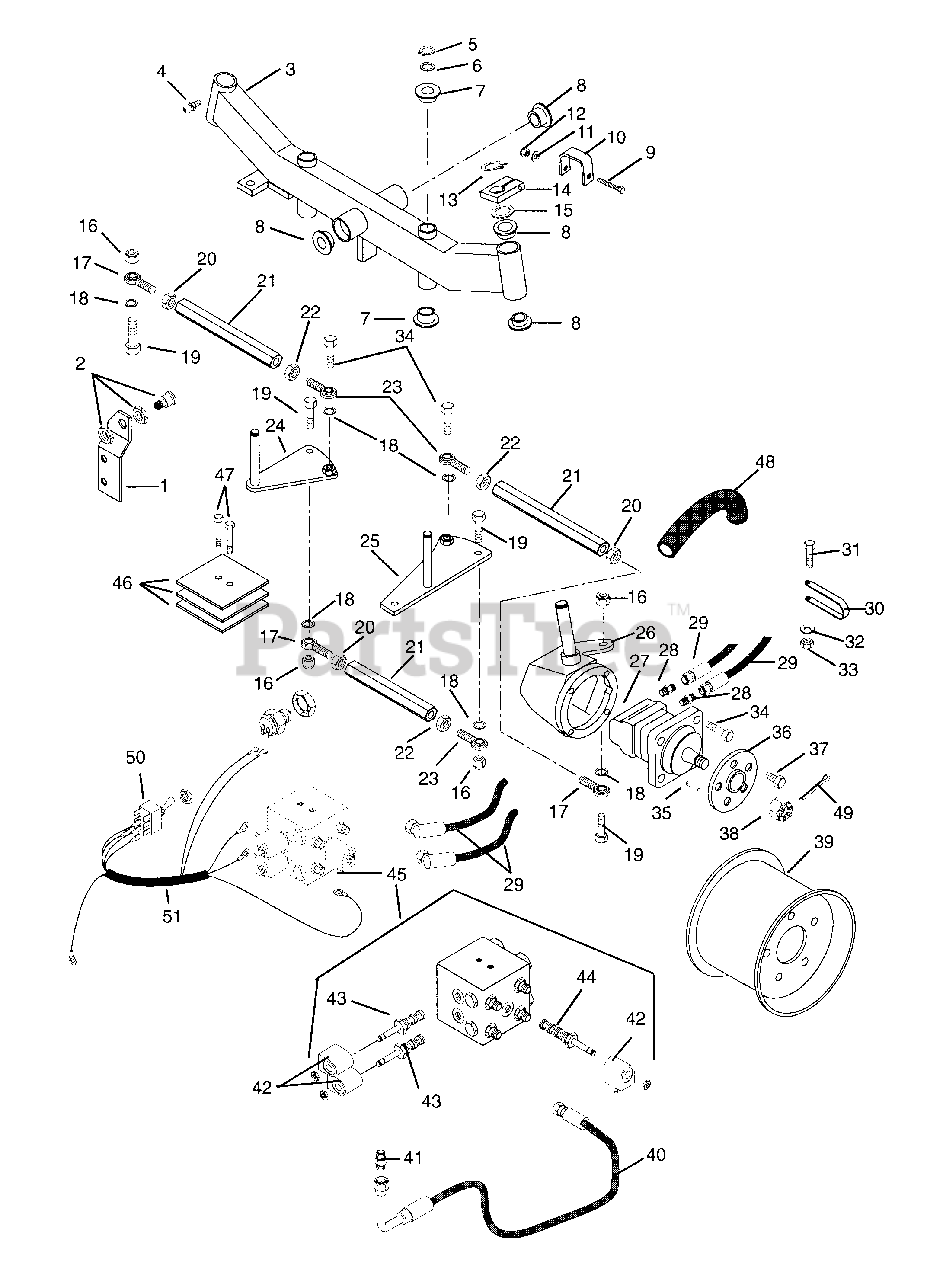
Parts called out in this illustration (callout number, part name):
2	Safety Switch
3	Axle Weldment
4	Fitting Lube .25-28 x .256
5	Ring-Retaining-External .689 x .077
6	Bearing-Needle-Thrust .752 x 1.24 x .031
7	Bushing-Flange .762 x 1.0 x .580 x 1.48
8	Bushing-Flange 1.020 x 1.385 x .75 x 1.75
9	Bolt-Hex .25-20 x 2.75 Grade 5
10	Bracket, Hose Loop
11	Washer-Flat-Steel .281 X .62 X .065
12	Nut-Locking .25-20
13	Ring-Retaining-External .906 x .078
14	Bracket Support
15	Washer-Hardened Thrust 1.002 x 1.552 x .030
16	Nut-Locking-Center .50-13 Grade 5
17	Assembly, Rod End Right Hand
18	Spacer .520 x .625 x .125
19	Bolt-Hex .50-13 x 2.00 Grade 5
20	Nut-Jam .50-20 Grade 2
21	Rod, Tie
22	Nut-Jam .50-20 Left Hand Grade 2
23	Assembly, Rod End Left Hand
24	Weldment, Steering Idler
25	Weldment, Steering Arm
26	Spindle Weldment Left Hand
26	Spindle Weldment Right Hand
27	Eaton 2000 Wheel Motor
28	Adapter, Hydraulic
29	Assembly, Hydraulic Hose
30	Clamp, Nylon
31	Bolt-Hex .38-16 x 1.00 Grade 5
32	Washer-Flat-Steel .406 x .812 x .065
33	Nut-Locking-Center .38-16
34	Bolt-Hex .50-13 x 1.50 Grade 5
35	Key-Square .313 x 1
37	Screw-Hex-Tapping .500-20 x .62
38	Nut-Hex Slotted 1-20
40	Assembly, Hydraulic Hose
41	Adapter, Hydraulic
42	Coil, Solenoid
43	Valve, 3-Way 12VDC Directional
44	Valve, 4-Way 12VDC Directional
45	Hydraulic Manifold Assembly
47	Bolt-Hex .31-18 x 1.25 Grade 5
48	Sleeve 18"
49	Pin-Cotter .12 x 2.0
50	Power Switch, four Wheel Drive
51	Wire Harness, 4 Wheel Drive
